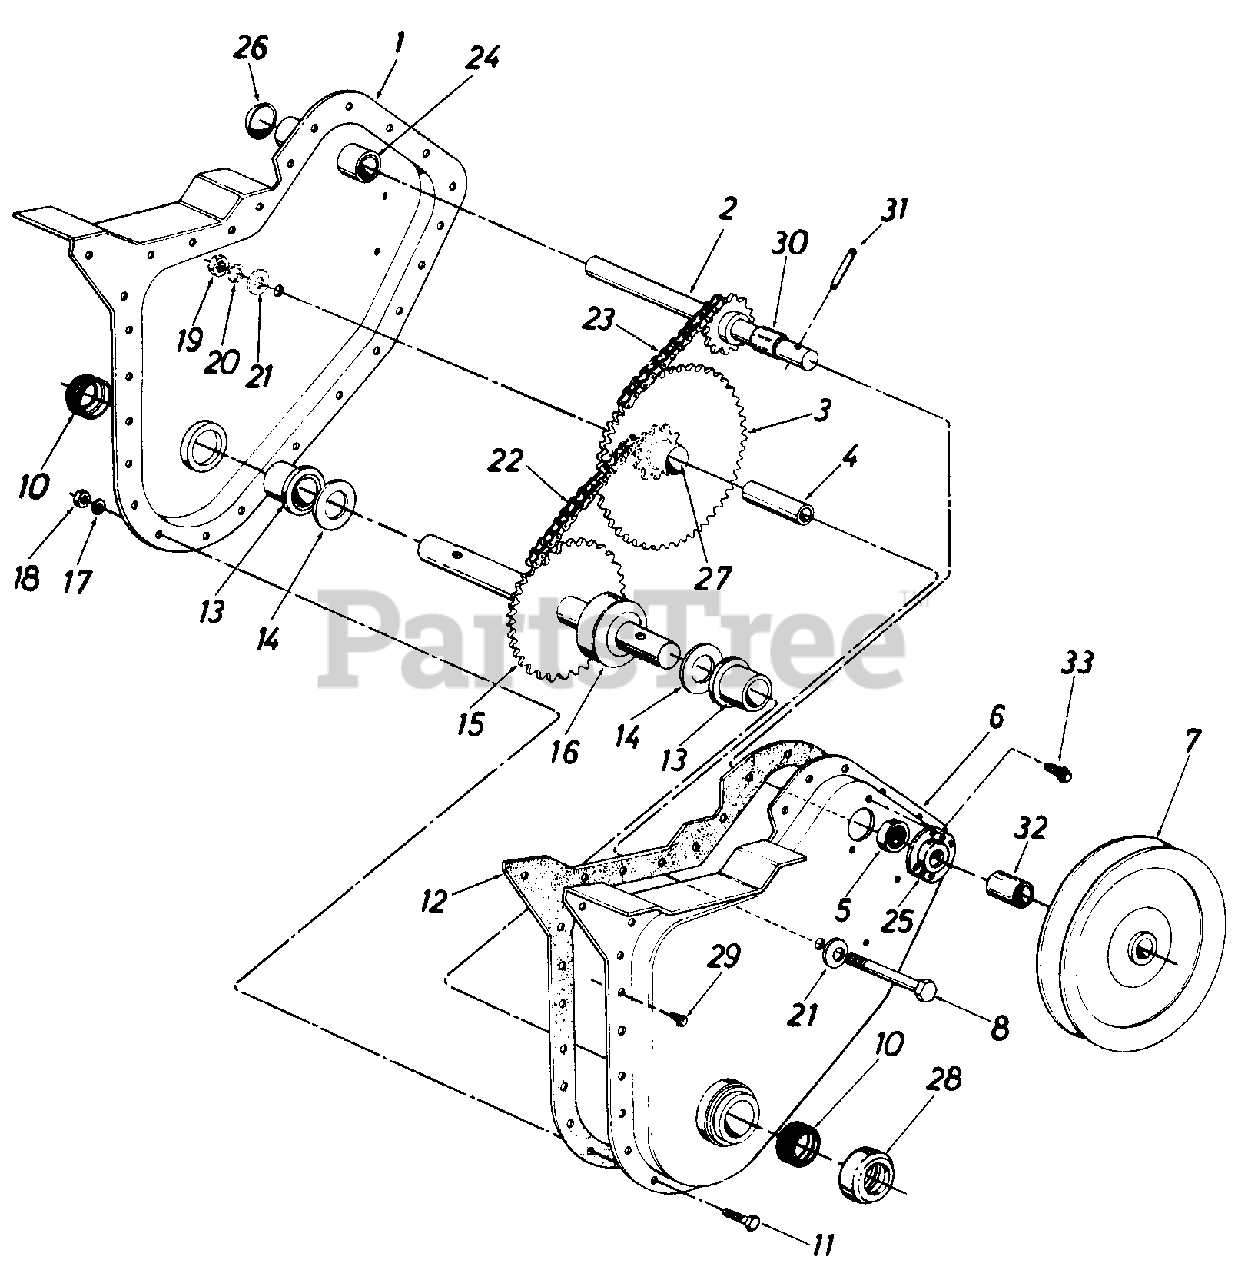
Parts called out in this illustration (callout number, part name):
1	Chain Case Ass'y.-R.H.
2	Input Shaft Ass'y.
3	Hub and Sprocket Ass'y.
4	Bearing Inner Race
5	Ball Bearing
6	Chain Case Ass'y.-L.H.
7	Pulley-Chain Case 51/2 x 1/2
8	Hex Bolt 3/8-24 x 2.50" Lg.
11	Hex Bolt 1/4-28 x .625" Lg.
12	Gasket
13	Flange Brg. .879 I.D.
14	Fl-Wash. .88 I.D. x 1.50 O.D. x .030
15	Tine Shatt Ass'y.
16	Spacer 7/8" I.D. x 2.0" O.D. x.68" Lg.
17	L-Wash. 1/4" Scr.*
18	Hex Nut 1/4-28 Thd.
19	Hex Ins. L-Nut 3/8-24 Thd.
20	L-Wash. 3/8" I.D.
21	Bell-Wash. .406 I.D. x 1.130 O.D.
22	Chain #420-.50" Pitch x 38 Links
23	Chain #35-.375" Pitch x 50 Links
24	Bearing .62" I.D. x .813 O.D. x 1.31
25	Bearing Housing
26	Expansion Plug 13/16" Dia.
27	Bearing
28	Dust Cap
29	Hex Wash. Hd. Self-Tap Scr. 1/4-20 x .50" Lg.
30	Spacer .630 I.D. x .77 O.D. x .38" Lg.
31	Spring Pin Spiral 1/4" Dia. x 1 1/2 " Lg.
32	Spacer .647 x 1.25"
33	Hex Wash. Hd. Self-Tap Scr. 1/4-20 x .38" Lg.
